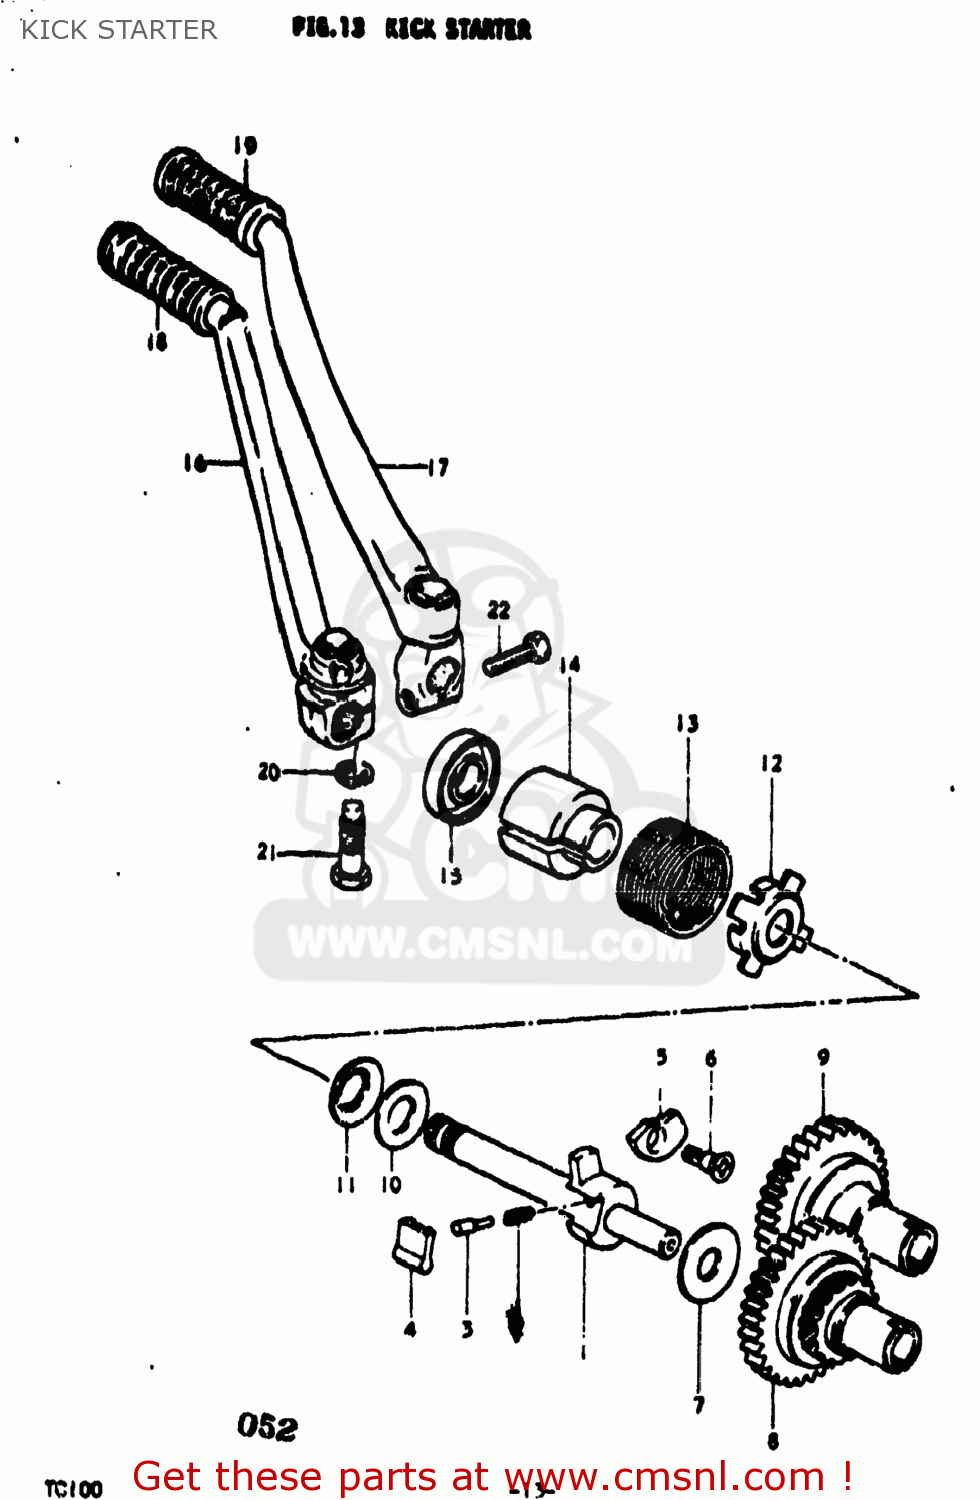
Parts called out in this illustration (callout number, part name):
1	SHAFT,KICK STARTER
2	SPRING
3	PIN(5X15.5)
4	PAWL,KICK STARTER
5	LIFTER,KICK STARTER PAWL
6	SCREW(6X19)
7	WASHER
8	GEAR,KICK STARTER DRIVE
9	GEAR,KICK STARTER DRIVE
10	WASHER(16X30X0.5)
11	WASHER
12	HOLDER,KICK SHAFT SPRING
13	SPRING
14	GUIDE,KICK SHAFT SPRING
15	SEAL,OIL(16X30X8)
16	LEVER ASSEMBLY,KICK STARTER
17	LEVER ASSEMBLY,KICK STARTER
18	RUBBER,KICK STARTER PEDAL
19	RUBBER,KICK STARTER PEDAL
20	LOCK WASHER
21	BOLT(10X37.5)
22	BOLT
